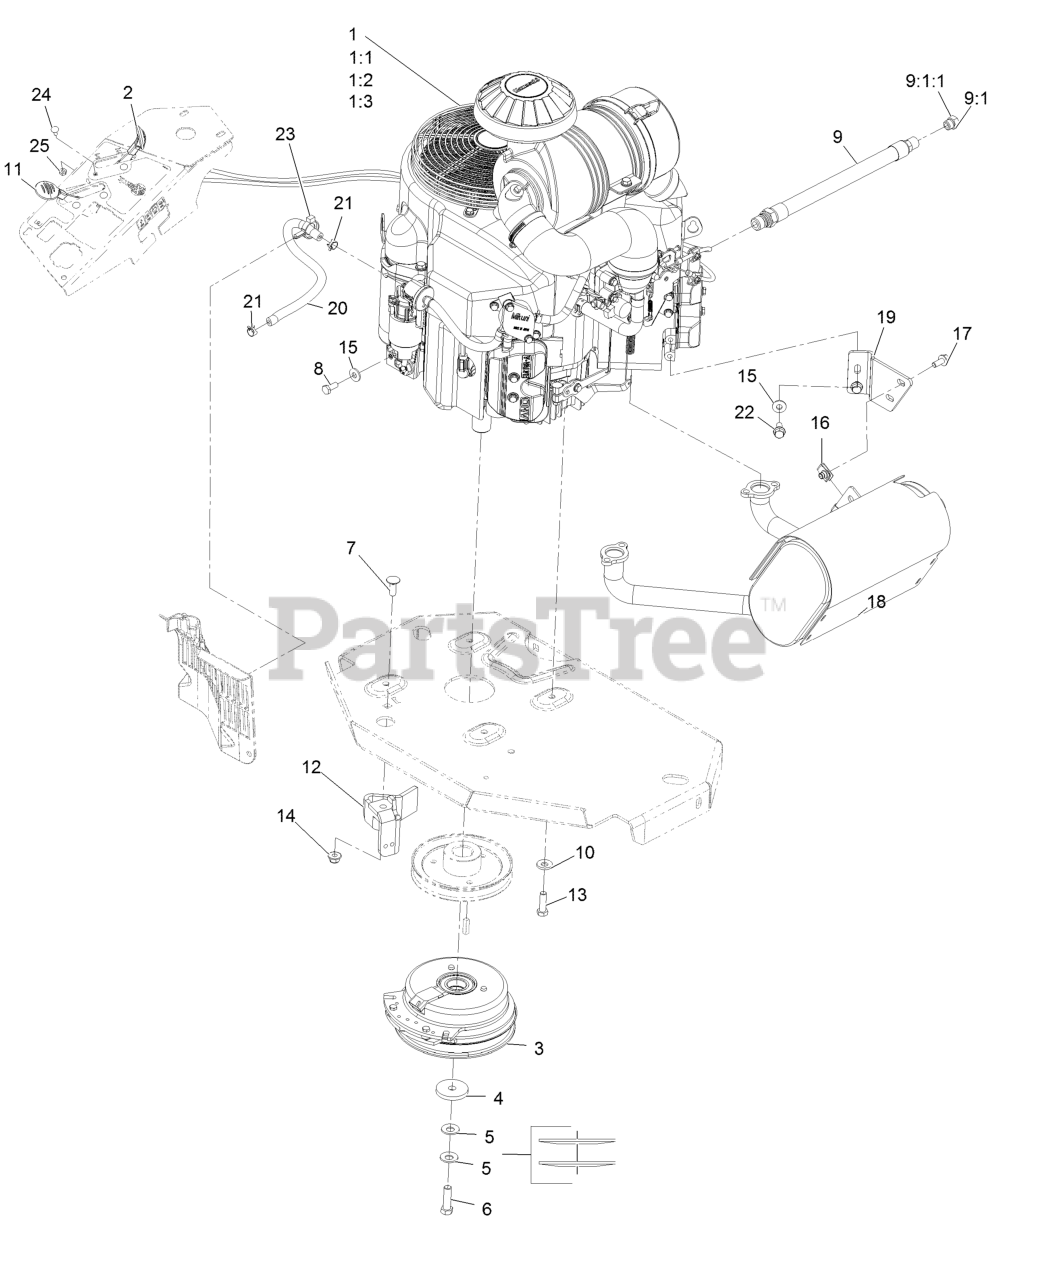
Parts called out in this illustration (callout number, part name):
1:1	Kawasaki 49065-2078 Engine Oil Filter
1:2	Kawasaki 11013-7044Engine Air Filter
1:3	Kawasaki 11013-7045 Safety Filter
2	ASM, Choke Cable
3	Clutch Kit
4	Washer-Clutch
5	Washer-Spring Disc 7/16
6	Screw-HH 7/16-20 X 1 1/2 W/Loctite
7	Bolt-Carriage 3/8-16 X 1
8	Screw-HH M8-1.25 X 20Mm
9	Asm-Hose Oil Drain W/Plug
9:1	Plug-W/O-Ring
9:1:1	O-Ring
10	Washer-Spring Disc 3/8
11	ASM,Throttle Cable
12	Clutch-Anchor
13	Screw-HH 3/8-16 X 1 1/4
14	Nut-Nyloc 3/8-16 Flg
15	Washer-Spring Disc 5/16
17	Screw-HH Flg 5/16-18 X 3/4
18	Muffler
19	Bracket-Muffler
20	Hose-Fuel Line 15"
21	Clamp-Hose
22	Screw-HH M8-1.25 X 20Mm
23	Clamp-Hose
24	Bolt-Carriage #10-24 X 1/2
25	Nut-Nyloc #10-24
